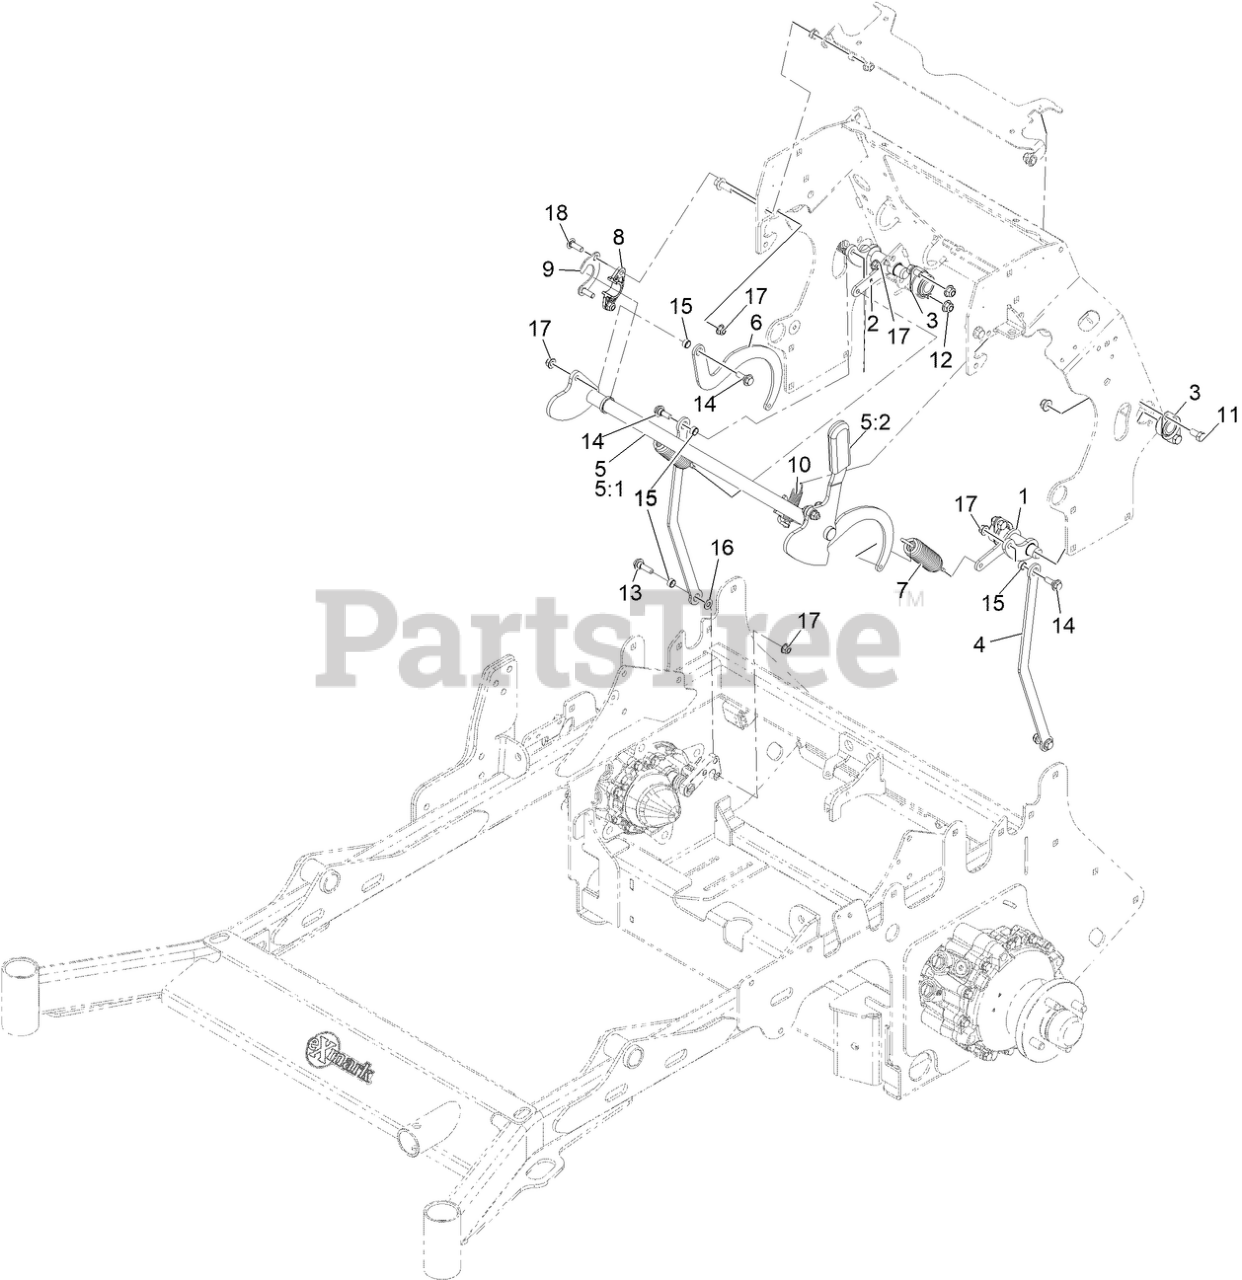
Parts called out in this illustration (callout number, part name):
1	ASM-LH BRAKE SHAFT
2	ASM-RH BRAKE SHAFT
3	BEARING-FLANGE, SIDE
4	LINK-PARK BRAKE, LOWER
5	ASM,PARK BRAKE HANDLE W/GRIP
5:1	ASM-BRAKE UPPER SHAFT
5:2	GRIP-LEVER
6	LINK-UPPER BRAKE
7	SPRING, EXTENSION
8	BEARING-FLANGE
9	SUPPORT, BEARING
10	SPRING-EXTENSION
11	SCREW-HH
12	NUT-HF, NI
13	SCREW-SHOULDER
14	SCREW-SHOULDER
15	BUSHING-IGUS 7/16X0.25
16	WASHER-PLAIN
17	NUT-HF, NI
18	SCREW-CARR
